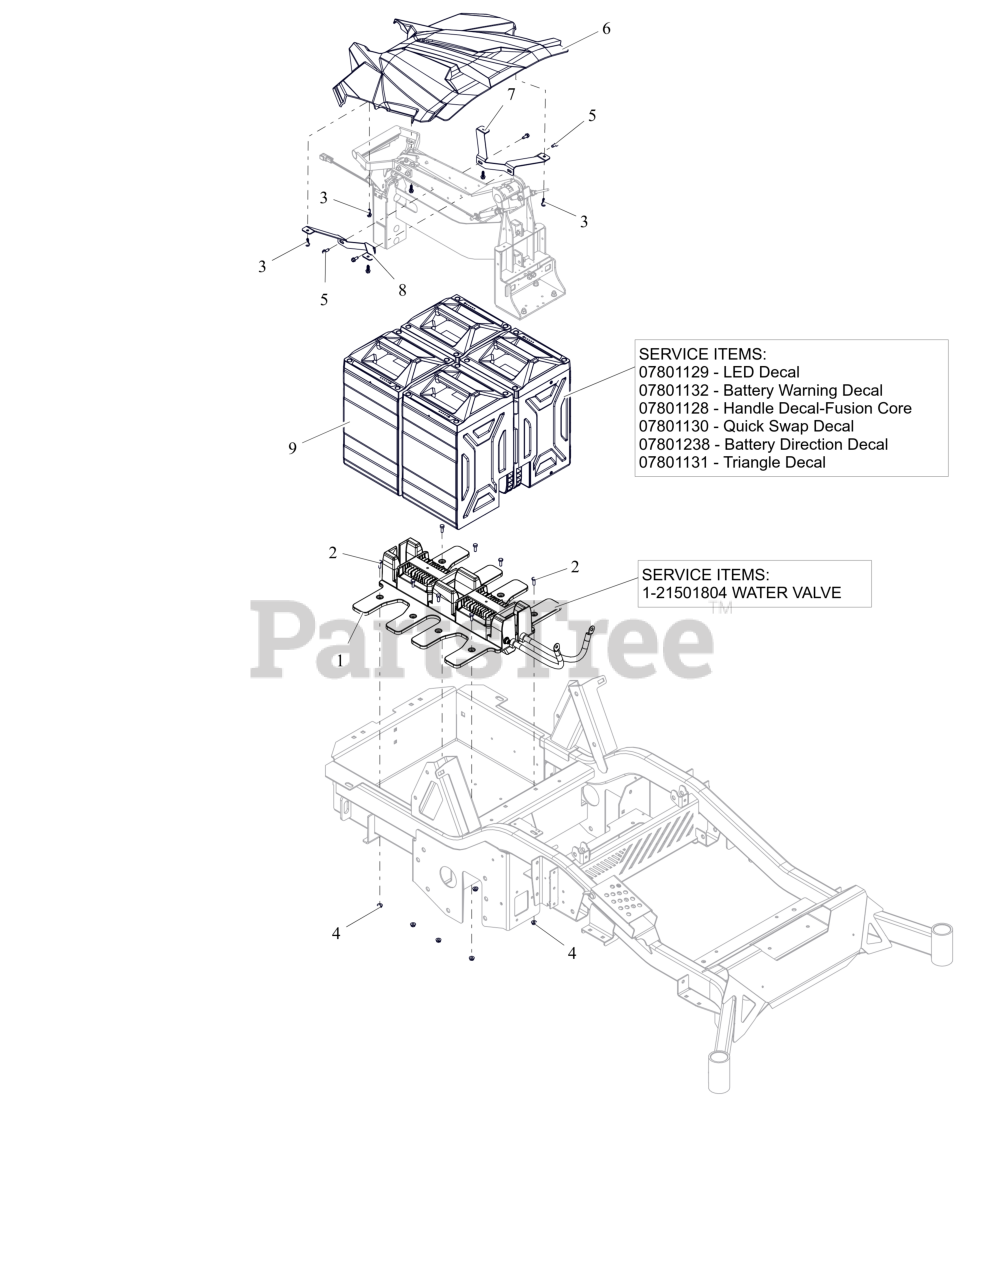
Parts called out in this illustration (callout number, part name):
1	BASE, BATTERY BUSSBAR
1	VALVE, WATER
2	BLT, HEX .25-20X.75 G5 ZCC
3	SCR, PLASTITE-HWH 0.25 X 0.75 ZC120
4	NUT-LK-CTR-FLG .25-20 ZC120
5	SCR,TAP .25-20X.625 HWH ZCC
6	HOOD, PRO - TURN EV
7	SUPPORT, HOOD EVZT (BLACK)
8	SUPPORT, HOOD EVZT (BLACK)
9	KIT, EV BATTERY
9	DECAL, BATTERY LED
9	DECAL, BATTERY WARNING
9	DECAL, BATTERY HANDLE
9	DECAL, BATTERY QUICKSWAP
9	DECAL, BATTERY INSTALL DIRECTION
9	DECAL, BATTERY OBLIQUE
